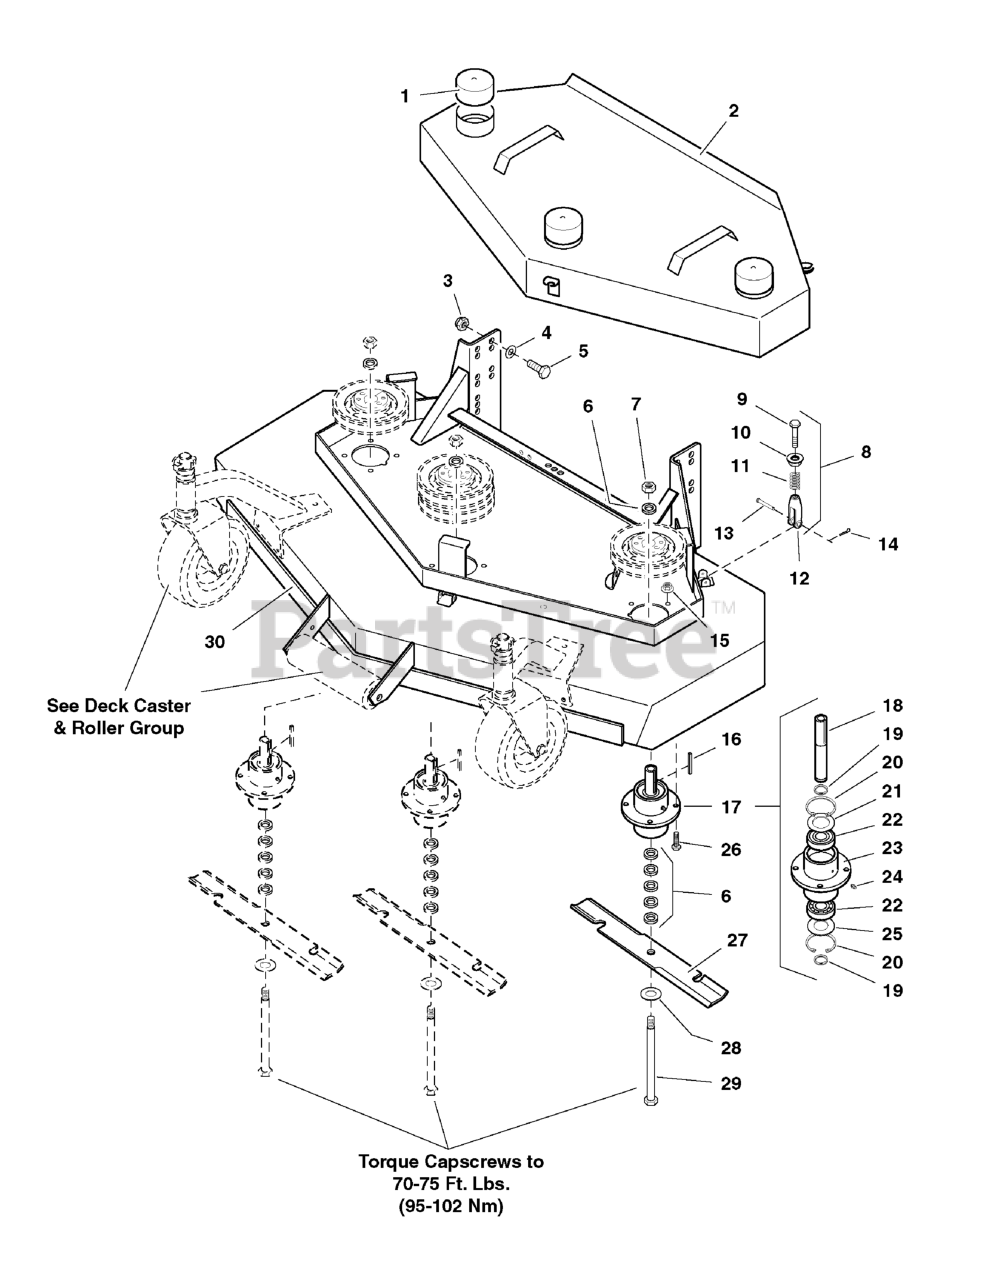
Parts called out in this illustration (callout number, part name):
1	VINYL CAP
2	SPINDLE COVER
3	NUT, Hex, Nylon Lock, 1/2-20
4	WASHER, 1/2 SAE
5	BOLT, 1/2-20 X 1-1/4" GD5 CZ
6	SPACER, .63 x 1.06 x .23
7	NUT, 5/8-11 Hex
8	GUARD HOLD DOWN ASSEMBLY
9	BOLT, 5/16-18 x 2
10	NUT, 3/8-16 Hex Serrated Flange
11	SPRING, Guard Hold Down
12	CLEVIS, 5/16-24, Plastic
13	CLEVIS PIN
14	COTTER PIN
15	NUT, 5/16-18 HEX SERRATED FLANGE (LARGE)
16	KEY, 1/4 SQ. X 2-1/2
17	SPINDLE ASSEMBLY, Complete
18	SPINDLE SHAFT
19	SNAP RING, External
20	SNAP RING, Internal
21	SPINDLE WASHER, Top
22	BEARING
23	SPINDLE HOUSING
24	GREASE FITTING
25	SPINDLE WASHER, Bottom
26	BOLT, 5/16-18 x 1-1/4
27	MOWER BLADE, 18"
28	WASHER, 5/8" USS
29	BOLT, 5/8-11 x 9-1/2
30	52" MOWER HOUSING ASSEMBLY
